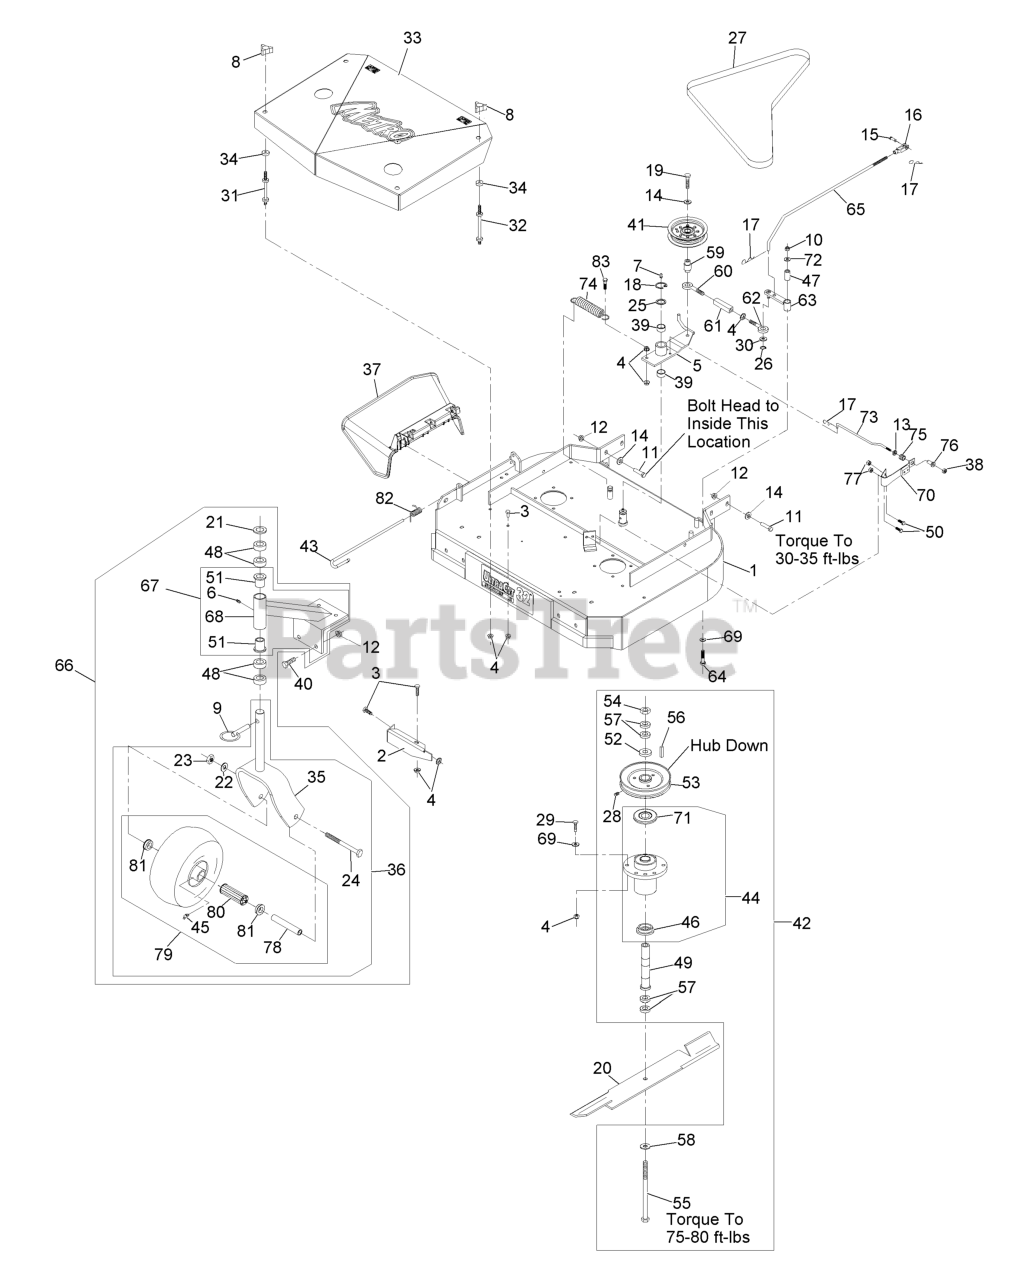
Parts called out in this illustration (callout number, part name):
1	ASM, DECK 32 RIGID
2	BAFFLE-DOGLEG
3	SCREW-HH
5	IDLER ARM ASM
6	FITTING-GREASE
7	FITTING-GREASE
8	KNOB-3 PRONG
10	NUT-LOCK, NI
11	SCREW-HH
12	NUT-HHF, WHIZ
13	RING-PUSH ON
14	WASHER-BELLEVILLE
15	PIN-CLEVIS
16	YOKE-ADJUSTABLE
17	PIN-COTTER
18	RING-RETAINING, EXT
19	SCREW-HH
21	WASHER-FLAT
22	WASHER-LOCK
23	NUT-HH
24	SCREW-HH
25	WASHER-SPINDLE
26	RING-RETAINING, EXT
27	BELT,BLADE METRO 32
28	SETSCREW
29	SCREW-HH
30	WASHER-PLAIN
31	STUD-SHIELD, BELT (SHORT)
32	STUD-SHIELD, BELT (LONG)
33	ASM,SHIELD W/DECALS 32 ME
35	FORK-CASTER
36	ASM,CASTER/WHEEL
37	CHUTE DEFLECTOR XRK M056
38	NUT-LOCK, NI
39	SLEEVE-BEARING
40	SCREW-HH
42	ASM, CUTTER HOUSING OUTER
43	PIN-CHUTE
44	KIT, CUTTER HOUSING
45	FITTING-GREASE
46	SPACER-GUARD, BOTTOM
47	TUBE-PIVOT
48	SPACER-CASTER
49	TUBE-SPINDLE, SHORT
50	SCREW-HH
51	BEARING-FLANGED
52	WASHER-RETAINER, SHEAVE
54	NUT-HEX
55	SCREW-CAP, HH
58	WASHER-SPRING
59	BUSHING-ENGAGEMENT
60	EYEBOLT-THREAD, LH
61	BODY-TURNBUCKLE
62	EYEBOLT-THREAD, RH
63	ARM-ASSIST, 32/36
64	SCREW-HH
65	ARM-ASSIST, LINKAGE
66	ASM,CASTER/MOUNT
67	SUPPORT ASM
69	WASHER-SPRING
70	PAD AND SPRING ASM
71	GUARD-BEARING, TOP
72	WASHER-FLAT
73	ROD-BRAKE
74	SPRING-EXTENSION
75	SPRING-COMPRESSION
76	SPACER-FLANGED
77	NUT-LOCK, NI
79	KIT, SP CASTER WHEEL REPL
80	BEARING
81	BUSHING
82	SPRING, TORSION
83	SCREW-HH, SPECIAL
